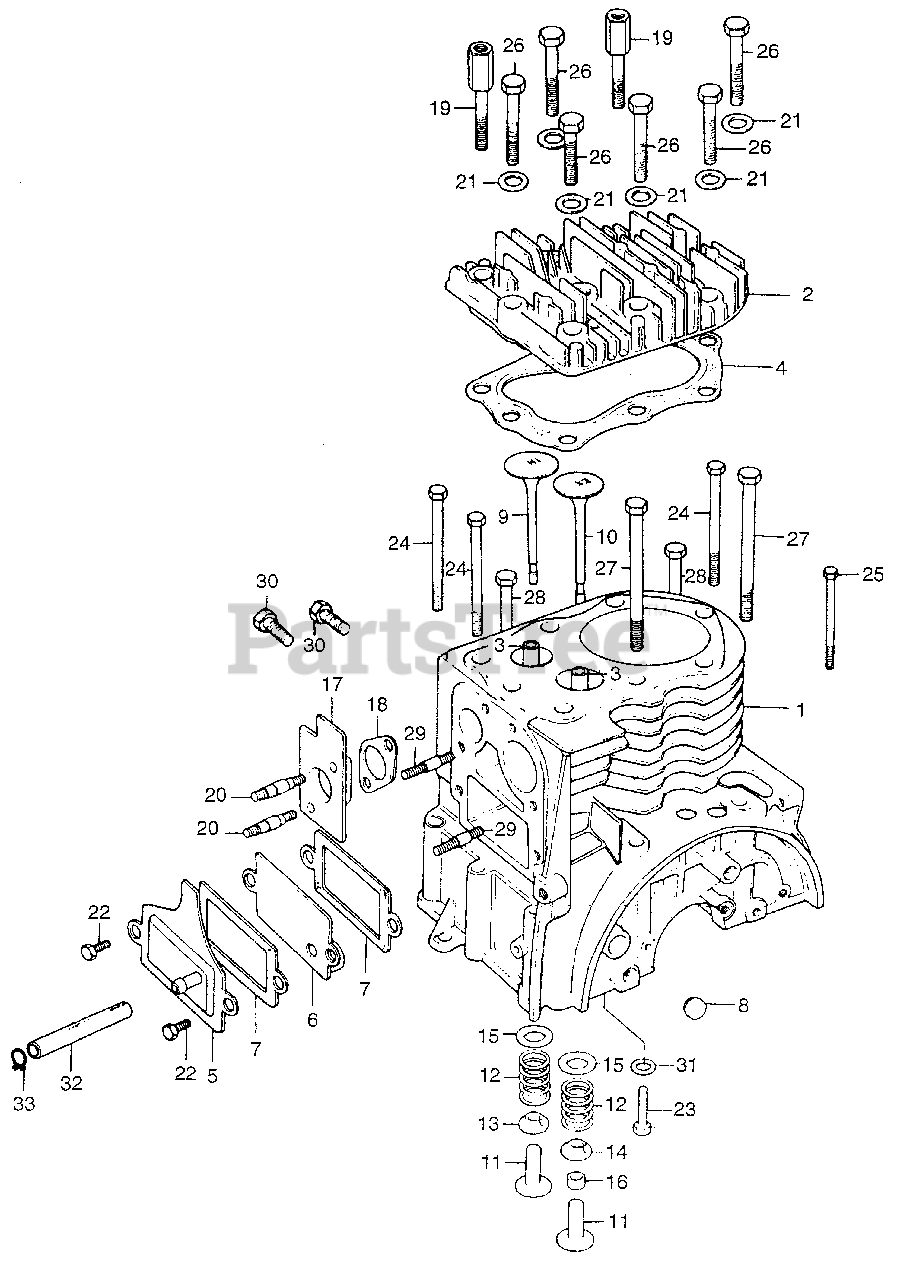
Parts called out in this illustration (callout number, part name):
1	CYLINDER
2	CYLINDER HEAD (NOT AVAILABLE)
4	GASKET, CYLINDER HEAD (NOT AVAILABLE)
5	COVER, TAPPET
6	SEPARATOR, OIL
7	GASKET, BREATHER CASE
8	PLUG, CAMSHAFT SEALING (NOT AVAILABLE)
9	VALVE, IN. (NOT AVAILABLE)
10	VALVE, EX. (NOT AVAILABLE)
11	LIFTER, VALVE
12	SPRING, VALVE (NOT AVAILABLE)
13	RETAINER, VALVE SPRING
14	RETAINER, VALVE SPRING (NOT AVAILABLE)
15	SEAT, SPRING (NOT AVAILABLE)
15	SEAT, VALVE SPRING
16	ADJUSTER, TAPPET CLEARANCE (5.2/5.3) (NOT AVAILABLE)
16	ADJUSTER, TAPPET CLEARANCE (5.5/5.6) (NOT AVAILABLE)
16	ADJUSTER, TAPPET CLEARANCE (5.9/6.0) (NOT AVAILABLE)
17	INSULATOR, CARBURETOR (NOT AVAILABLE)
18	GASKET, CARBURETOR INSULATOR (NOT AVAILABLE)
19	BOLT, STUD (8X39)
20	BOLT, STUD (8X39)
21	WASHER, HEAD (8MM)
22	BOLT, HEX. (6X16)
23	BOLT, HEX. (6X32)
24	BOLT, HEX. (6X71) (NOT AVAILABLE)
26	BOLT, HEX. (8X36)
27	BOLT, HEX. (8X70)
27	BOLT, HEX. (8X70) (NOT AVAILABLE)
28	BOLT, HEX. (8X100)
29	BOLT, STUD (6X18)
30	SCREW, OVAL (6X32)
31	WASHER, PLAIN (6MM)
32	BULK HOSE, FUEL (8X1000) (8X85)
33	CLIP, TUBE (B12.5)
